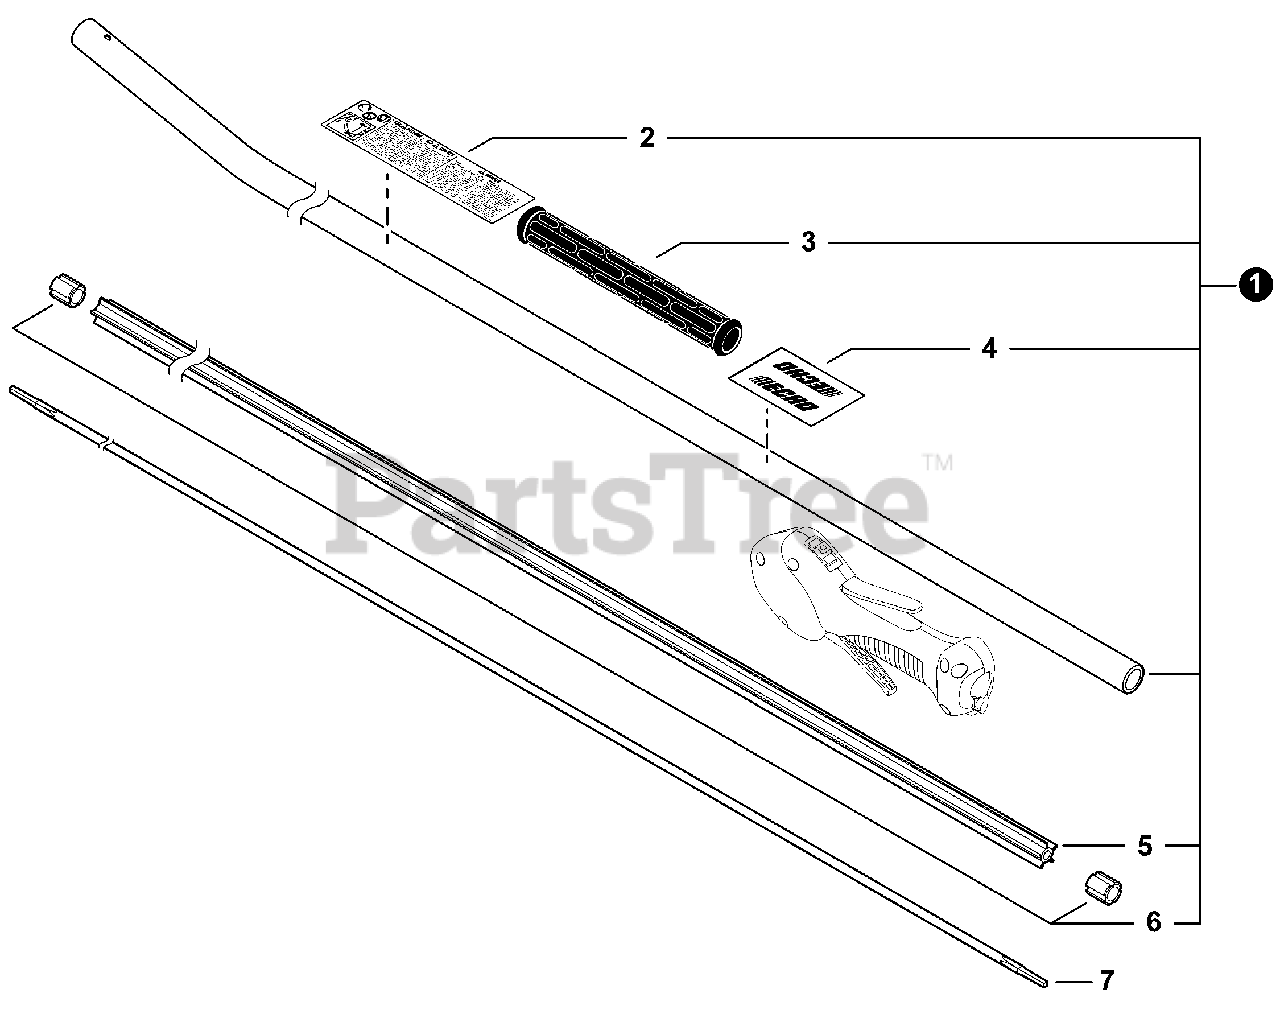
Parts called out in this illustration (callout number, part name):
1	MAIN PIPE ASSY
2	LABEL, CAUTION
3	GRIP, FRONT
4	LABEL, HANDLE LOCATION
5	LINER - FLEXIBLE
7	DRIVESHAFT - FLEXIBLE
